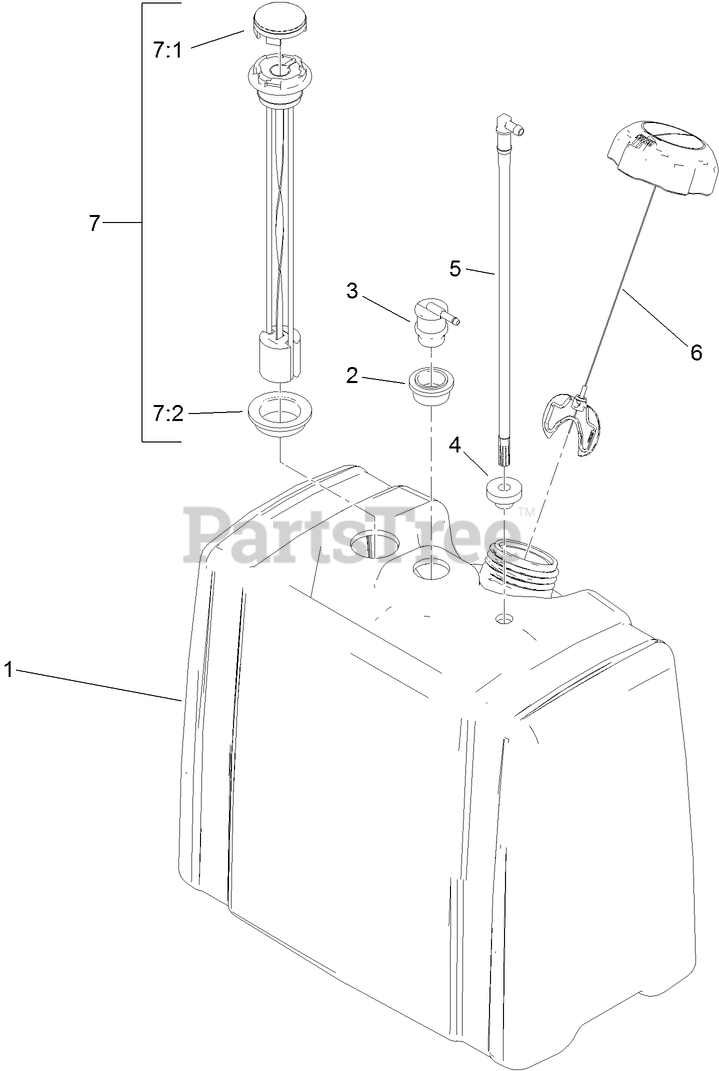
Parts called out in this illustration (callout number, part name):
1	TANK-FUEL
2	GROMMET
3	VALVE-ROLLOVER
4	BUSHING
5	PIPE-STAND
6	CAP-FUEL
7	GAUGE ASM
7:1	DIAL-GAUGE
